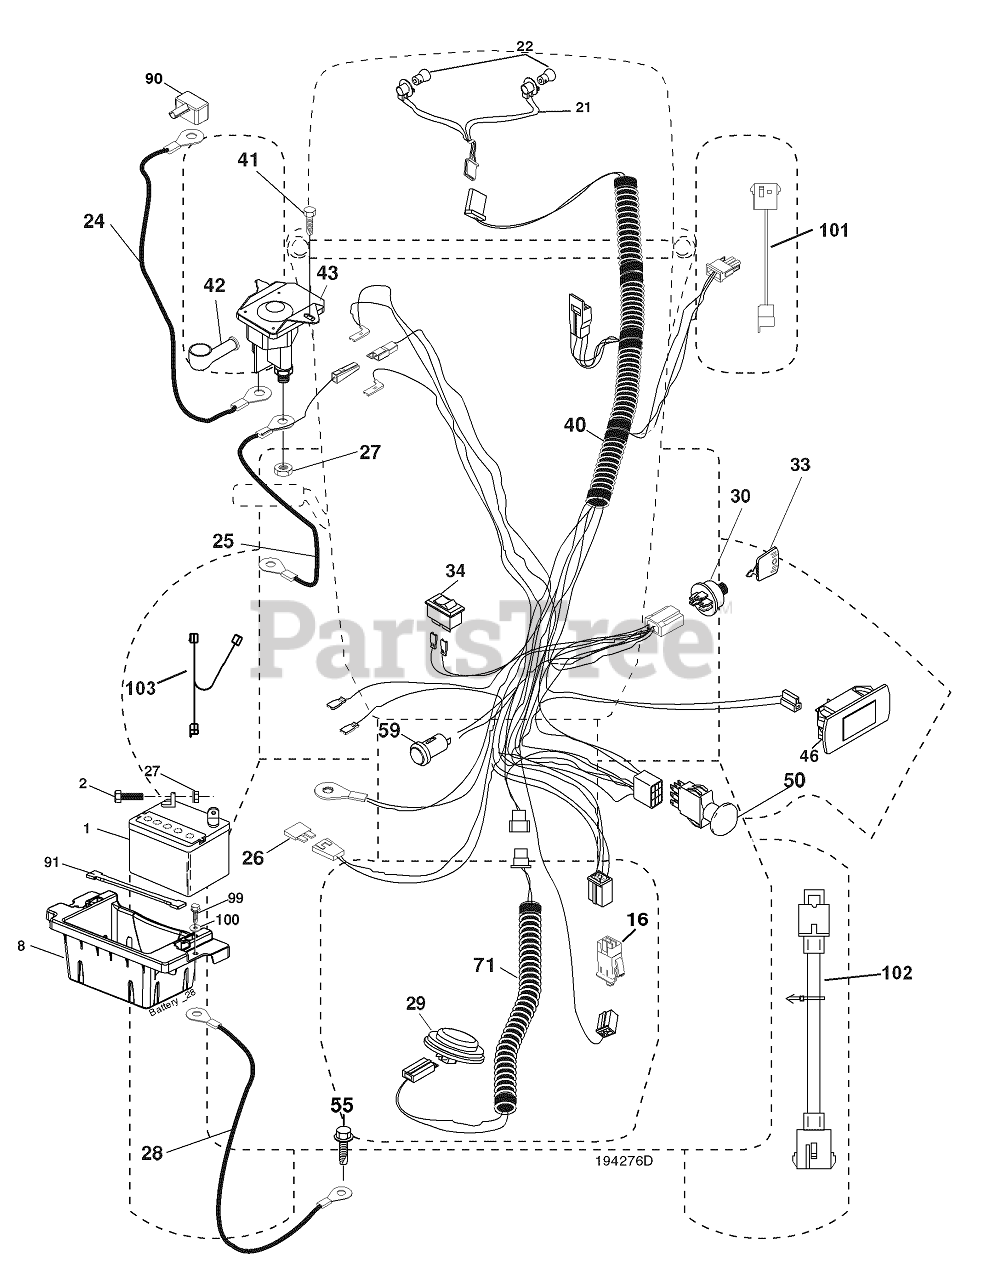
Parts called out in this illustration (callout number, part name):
1	Battery
2	Bolt Hex Hd 1/4-20 unc x 3/4
8	Battery Box
16	Switch Interlock
21	Harness Socket Light
22	Bulb, Light # 1156
24	Cable Battery
25	Cable Starter
26	Fuse
27	Nut Keps Hex 1/4-20 unc
28	Cable Ground 21" Blk 6 Ga.
29	Switch Seat
30	Switch Ign
33	Key Ign Molded Generic
34	Switch Light/Reset
40	Harness Ign. Dash
41	Screw Thd Cut 1/4-20 x 1/2
42	Cover Terminal Red
43	Solenoid
46	Gauge Hourmeter
50	Switch PTO
55	Screw Thdrol 5/16-18 x 3/4
59	Outlet 12-Volt
71	Harness Ign
90	Cover Terminal Battery
91	Strap Battery
99	Screw Hexwsh Thdrol 1/4-20 x 3/4
100	Washer 9/32 x 7/8 x 16 Ga.
101	Pigtail MATNLK
102	Harness Pigtail K46 Te x ROS
103	Harness Pigtail 12V Outlet
